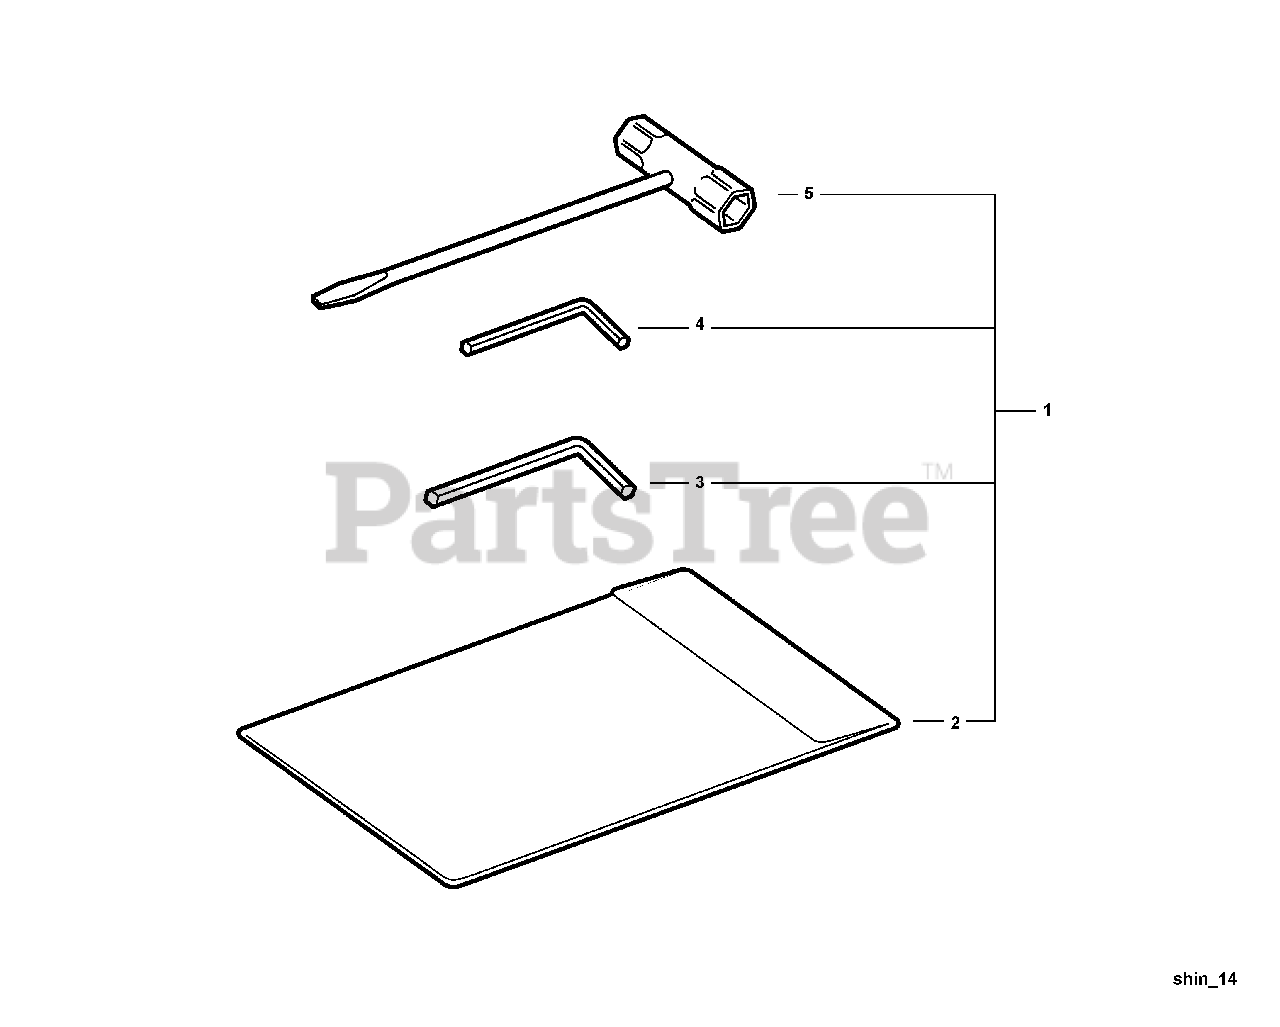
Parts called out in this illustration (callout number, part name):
1	TOOL KIT, SERVICE
2	WRENCH, ALLEN 3 MM
3	WRENCH, ALLEN 4 MM
4	T-WRENCH 13×19 MM
5	BAG, TOOL
